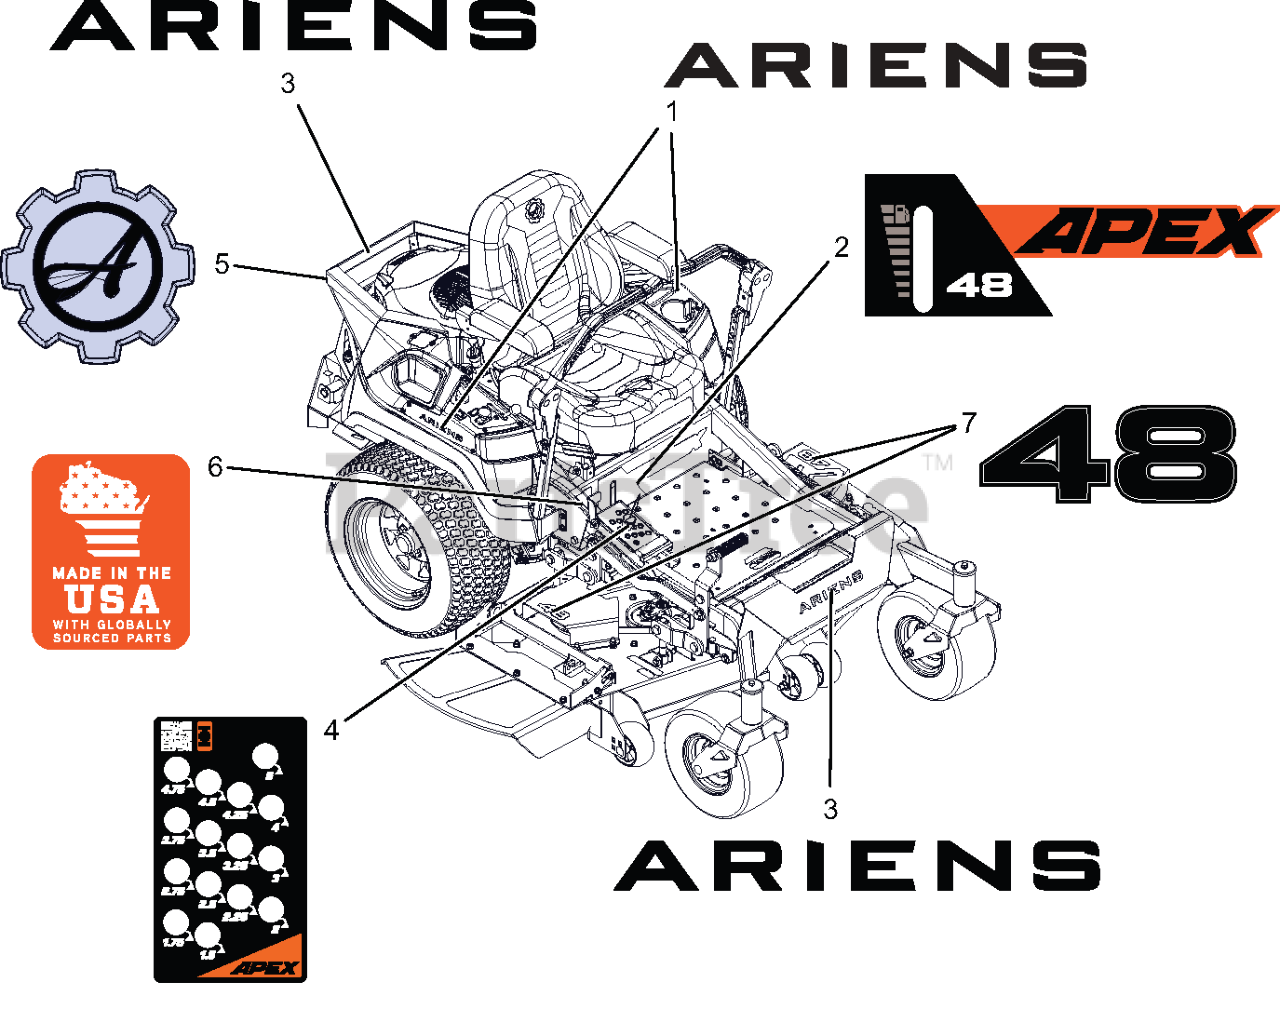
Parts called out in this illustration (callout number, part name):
1	DECAL- ARIENS 6.000" BLACK
2	DECAL- APEX 48 KICKPLATE
3	DECAL- ARIENS 9.625" BLACK
4	DECAL- APEX HOC
5	DECAL- ARIENS GEAR BADGE
6	DECAL- MADE IN USA
7	DECAL- DECK 48
